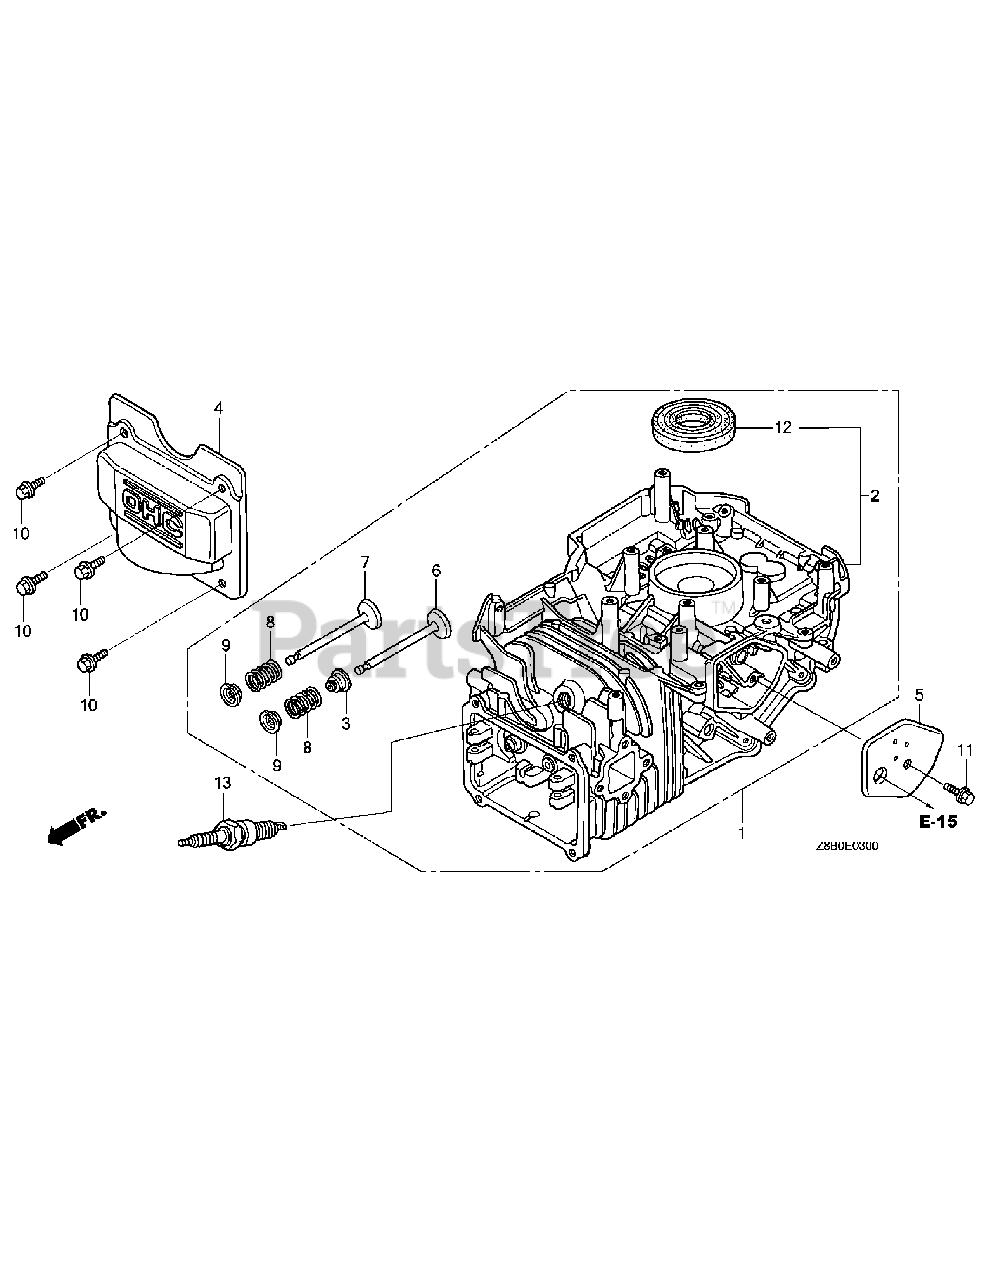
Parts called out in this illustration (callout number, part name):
1	CYLINDER ASSY.
3	SEAL, VALVE STEM
4	PRI; COVER, HEAD
4	SUP; COVER, HEAD
5	COVER, BREATHER
6	PRI; VALVE, IN. (ROCKNEL)
7	VALVE, EX.
8	SPRING, VALVE
9	RETAINER, VALVE SPRING
10	BOLT, FLANGE (6X12) (CT200)
11	BOLT, FLANGE (6X14) (CT200)
12	OIL SEAL (25.4X62X6)
13	SPARK PLUG (BPR6ES) (NGK)
